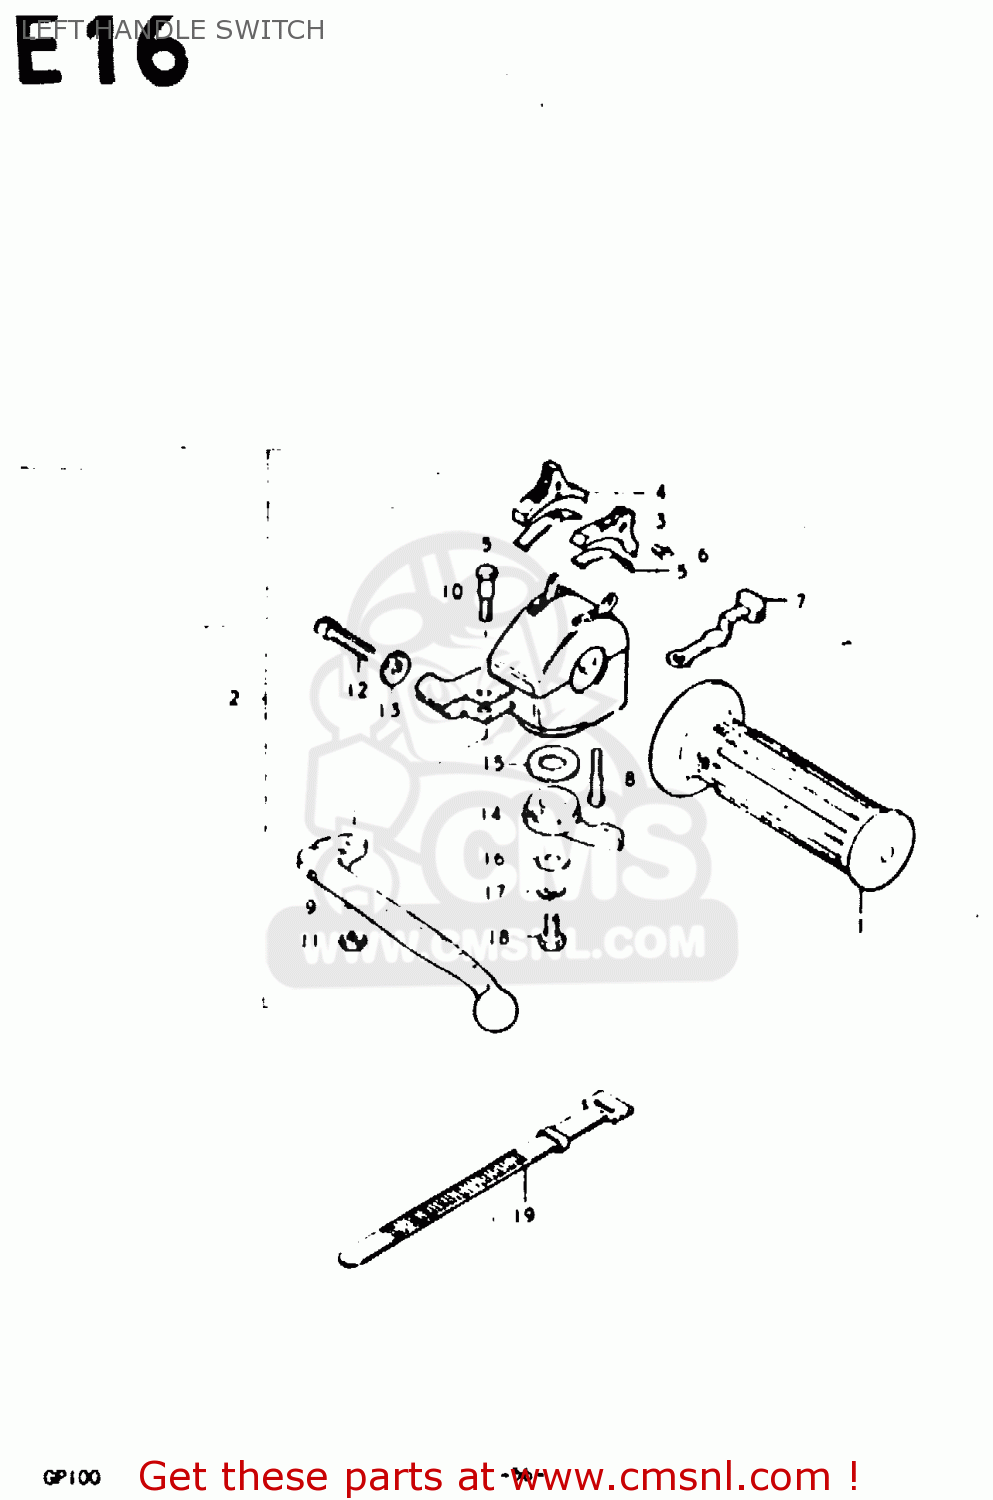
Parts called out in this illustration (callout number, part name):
1	GRIP,L
2	LEVER ASSY,CLUTCH
3	KNOB,HANDLE SWITCH
4	KNOB,HANDLE SWITCH
5	PLATE,SWITCH KNOB
6	SCREW
7	KNOB,TURN SIGNAL SWITCH
8	SCREW 5X20
9	LEVER,CLUTCH
10	BOLT
11	NUT
12	ADJUSTER,CABLE
13	NUT,CABLE ADJUSTER
14	LEVER,STARTER
15	WASHER,ADJUSTER
16	WASHER,STARTER LEVER
17	LOCK WASHER
18	BOLT
19	CLAMP(L:120)
